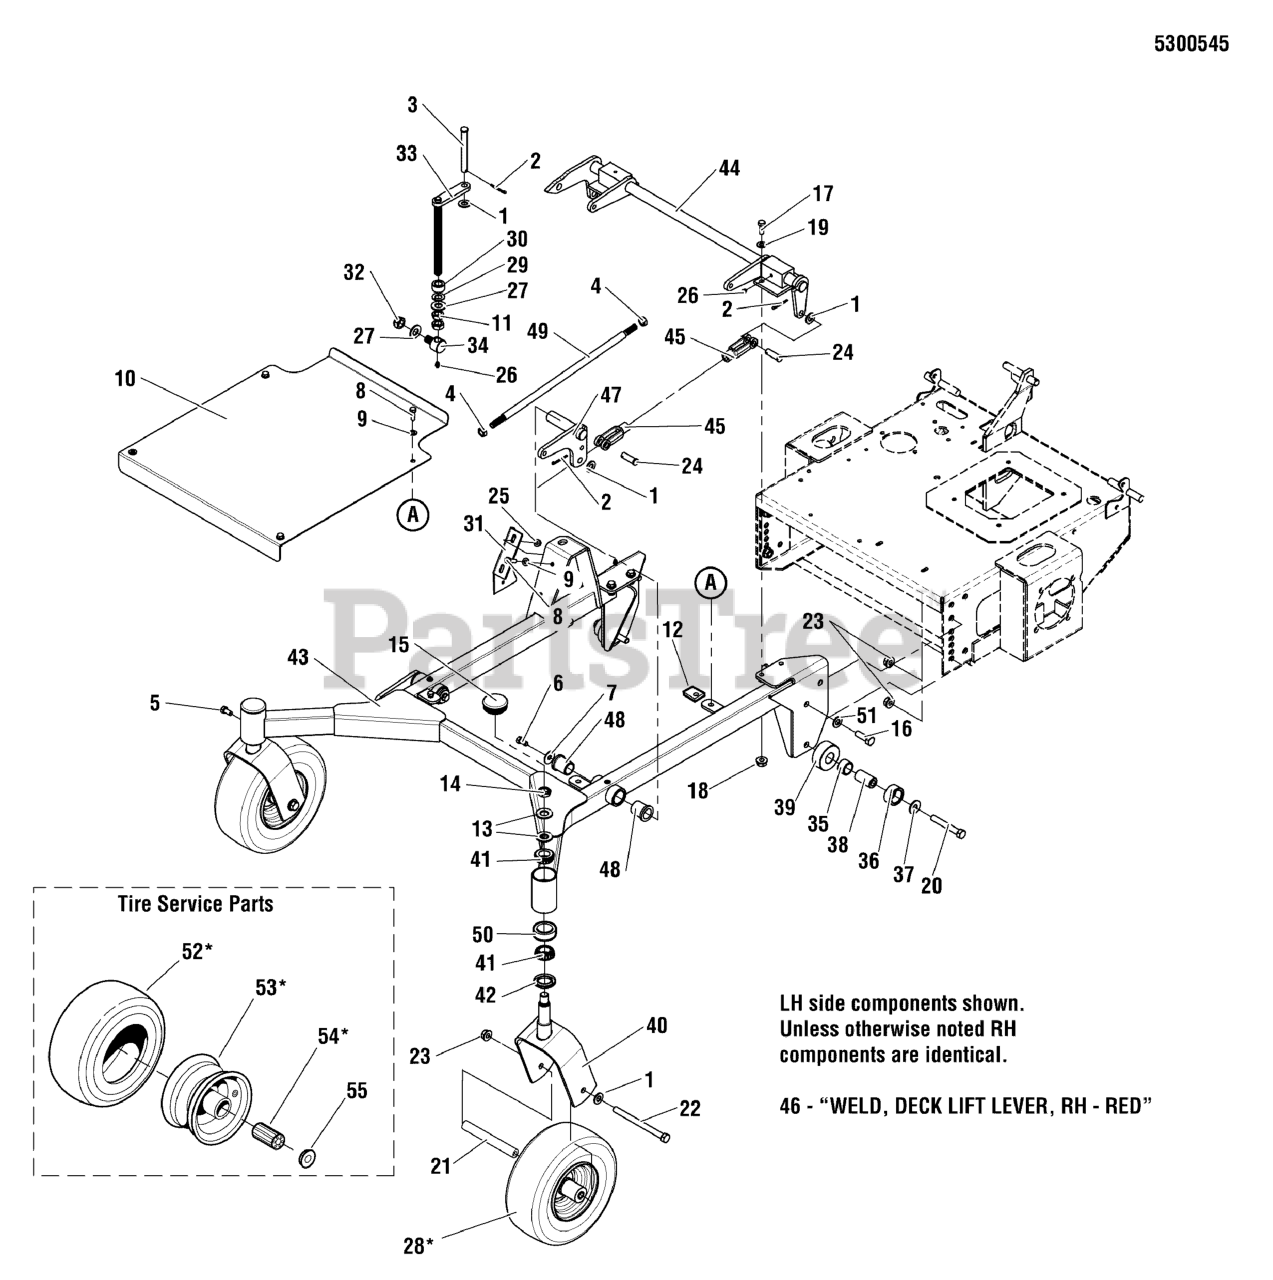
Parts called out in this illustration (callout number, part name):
1	WASHER, 1/2 SAE
2	* PIN, COTTER, 1/8" X 3/4
3	PIN CLEVIS 1/2" X 4-1/2" PLT
4	NUT, 1/2-20 Hex Jam
5	BOLT, 1/4-28 X 1/2, GD5 YZ
6	BOLT, 3/8-16 X 3/4, PLT W/PATCH
7	WASHER, .390 X 1.50 X .109, YZ
8	BOLT, 5/16-18 X 1" GRD5 YZ
9	WASHER, 5/16" SAE
10	GUARD, DECK, 61", MIDDLE, TWR - RED
11	NUT, 5/8-18, HEX JAM
12	BODY CLIP, 5/16-18 -1/4 MATERIAL
13	WASHER, BELLEVILLE - 1.500 X .755
14	NUT, 3/4-16, HEX JAM NYLON LOCK
15	CAP, GREASE, LOW PROFILE
16	BOLT, 1/2-13 X 1-1/2 GD5 CZ
17	BOLT, 3/8-16 X 1-1/4" GD5 CZ
18	NUT, 3/8 - 16 HEX NYLOCK FLANGE
19	WASHER, 3/8 SAE
20	BOLT, 1/2-13 X 3-1/2, HEX HD, GD5, CZ (SV)
21	AXLE, Front Caster
22	BOLT, HEX, 1/2-13 X 7, GD 8, YZ
23	NUT, Hex Flange, Nylock, 1/2-13
24	CLEVIS PIN, 1/2 X 1.36 SAE STANDARD
25	NUT, 5/16-18 HEX NYLOCK FLANGE NUT
26	GREASE FITTING, 1/4-28 Straight
27	WASHER, 5/8" SAE
29	WASHER, THRUST, .63 X 1.13 X .06
30	SPACER, .64 X 1.13 X .63, CZ
31	PLATE, HEIGHT INDICATOR - RED
32	NUT, Hex Jam, Nylon Lock, 5/8-11
33	HANDLE, CRANK, TWR
34	PIVOT, DECK LIFT
35	BUSHING, SLEEVE, 1.00 X 1.25 X .75
36	ROLLER, 1.256 X 1.75 X .813
37	WASHER, 1/2" USSZ
38	SPACER, .52 X 1.00 X 1.88 - SS
39	GUIDE, DECK - TWR
40	WELD., FRONT CASTER YOKES - RED
41	BEARING, TAPERED ROLLER, 1"
42	SEAL, GREASE
43	WELD, DECK MOUNT FRAME - RED
44	WELD, REAR LIFT SHAFT - RED
45	CLEVIS, 1/2-20, STEEL, CLEAR ZINC
46	WELD, DECK LIFT LEVER, RH - RED
47	WELD, DECK LIFT LEVER, LH - RED
48	BUSHING, FLANGE
49	ROD, DECK LIFT, 19.25, CZ
50	CUP, BEARING (SV)
51	WASHER, 1/2" GD9 YZ
52	TIRE, FRONT, 11 X 4.0 - 5 (SV)
55	RETAINER, BEARING (TWO PER TIRE)(SV)
